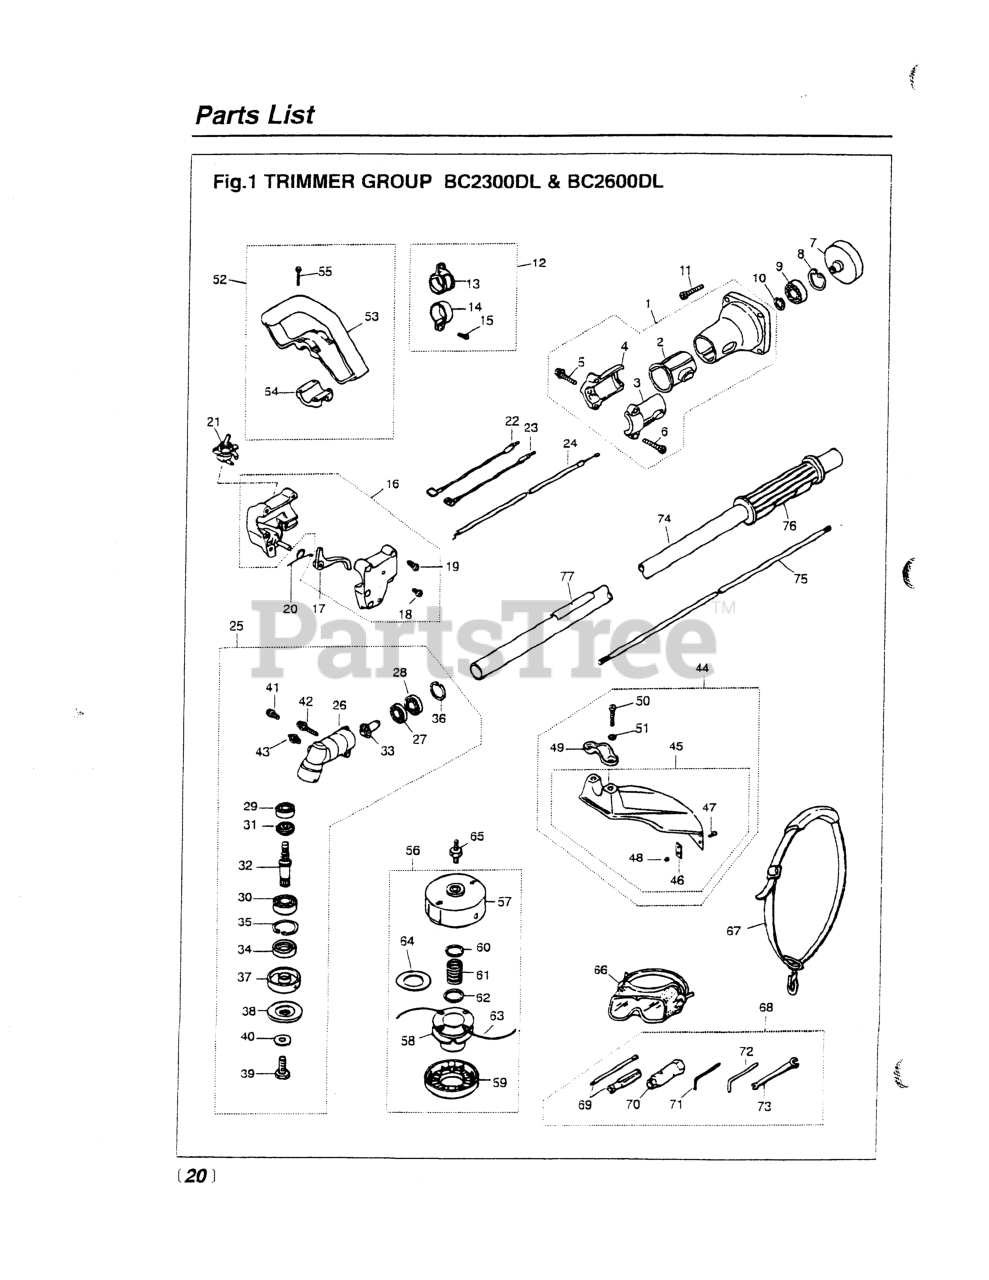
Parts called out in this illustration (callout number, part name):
2	CUSHION
3	BRACKET (USE -31211)
4	BRACKET (USE -31221)
5	BOLT (USE 3310-31720)
6	BOLT, M5 X 30
8	RING, SNAP, M28 x 1.2
9	BEARING
10	RING, SNAP (RPLS 3130-13270)
11	BOLT, M6 x 20
12	HANGER COMPLETE
13	HANGER
14	CLAMP
15	SCREW, M5 x 25
17	LEVER, THROTTLE
18	SET SCREW, ANTI-ROTATION
19	SCREW
20	SPRING, THROTTLE TRIGGER
21	SWITCH, STOP
22	CORD, RED (LEAD WIRE)
23	CORD, BLACK (LEAD WIRE)
24	CABLE COMP (RPLS 6460- )
25	GEARCASE ASSEMBLY
26	GEARCASE
27	BEARING
28	BEARING
29	BEARING
30	BEARING
31	GEAR
33	PINION
34	SEAL, OIL
35	RING, SNAP
36	RING, SNAP
37	HOLDER (A)
38	HOLDER (B)
40	WASHER
41	BOLT, M5 x 12
42	BOLT, M5 X 25
43	FITTING, GREASE
44	GUARD ASSEMBLY
46	BLADE
47	SCREW, M5 x 12
48	NUT
49	CLAMP
50	BOLT, M6 x 1.30
51	WASHER, M6 X 15
52	HANDLE ASSEMBLY
53	HANDLE
54	CLAMP
55	SCREW, M5 x 35
56	4
59	COVER (RPLS -15130)
60	PLATE, LARGE
62	PLATE, SMALL
63	CORD
64	SPACER
65	ARBOR, 8MM
66	GOGGLE
67	SHOULDER STRAP ASSY
68	TOOL SET
69	SCREWDRIVER
71	WRENCH (TOOL)
72	BAR
73	SPANNER, 8 X 10 (RPLS 2540- )
77	LABEL, BC2300/2600DL
